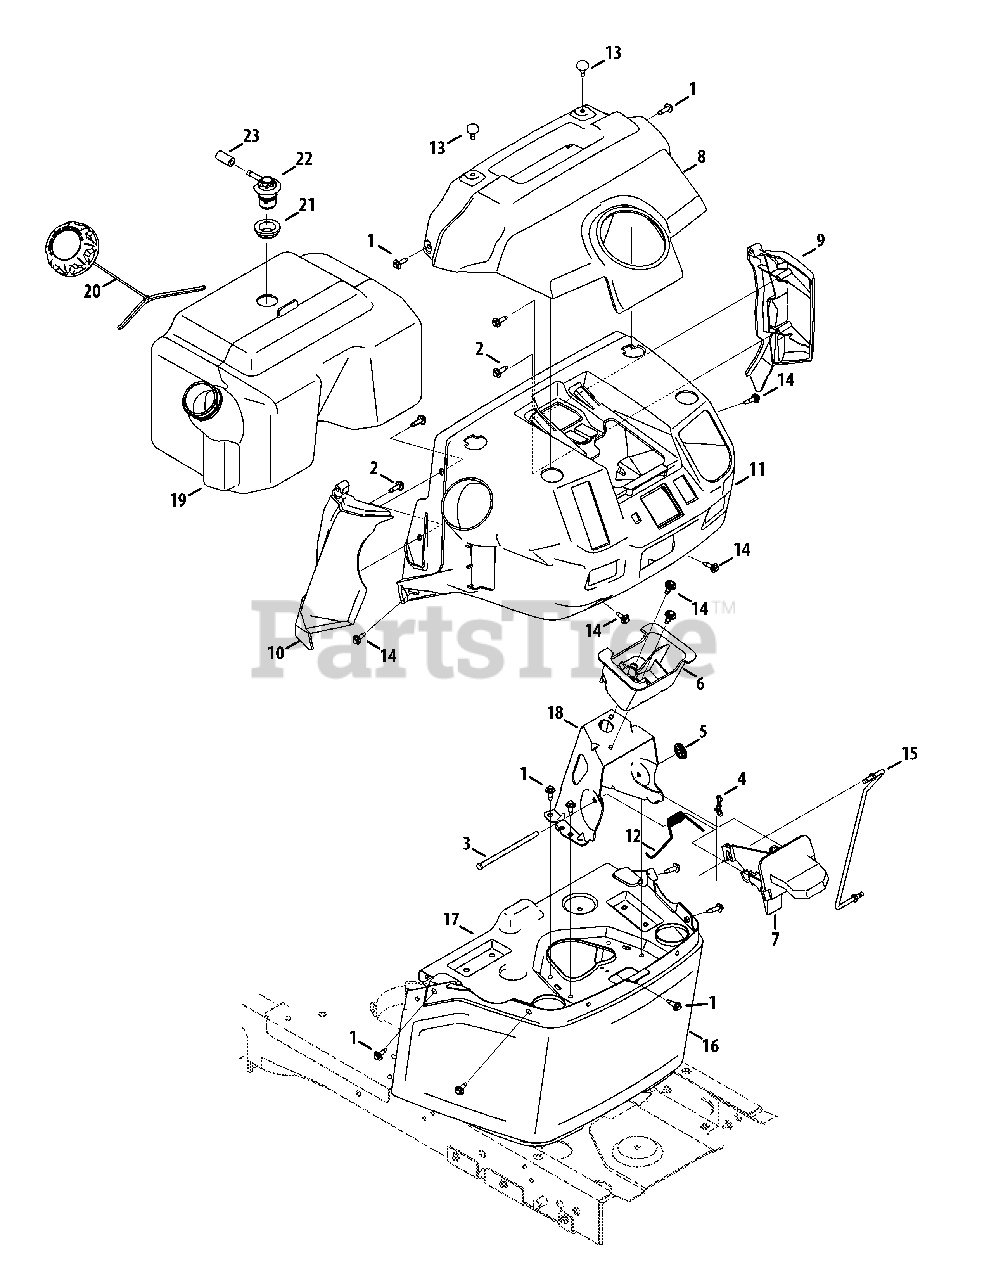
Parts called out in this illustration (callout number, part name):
1	Screw, M6-1 x .625
2	Screw, 1/4-10 x .75
3	Hinge Pin, .25 Dia x 4.50 LG
4	Pin, Cotter, Bow-Tie 72
5	Push Nut, .25 dia.
6	Steering Shaft Bearing
7	Dash Lever
8	Dash Cap
9	Dash Cap, RH
10	Dash Cap, LH
11	Upper Dash
12	Torsion Spring, .330 ID
13	Bumper, .62 Dia x .3
14	Shoulder Screw, .368 x .115, M6-1
15	Control Rod
16	Lower Dash
17	Dash Plate
18	Steering Bearing Mounting Bracket
19	Tank, Fuel, 3 Gal.
20	Fuel Cap
21	Grommet, Rubber, 23.0 ID
22	Valve, Rollover Grommet
23	Hose, Vent
